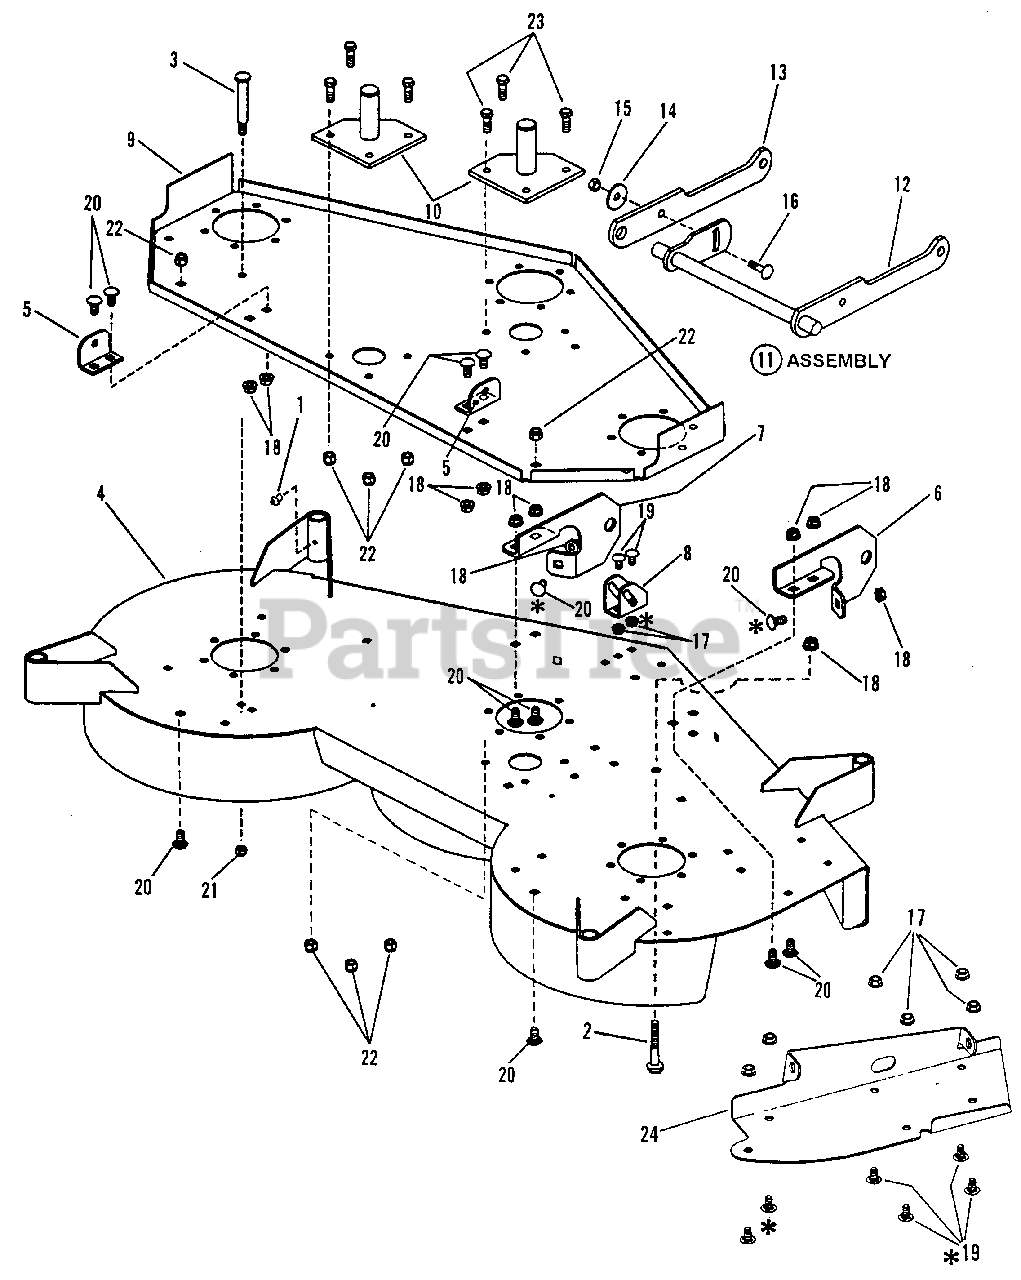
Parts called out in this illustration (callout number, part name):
1	LUBE FITTING, Straight (press-fit for .187 dia. Hole)
2	SCREW, 3/8-16 x 1-1/4" Hex Head Cap, Grade 5
3	BOLT, Gage Wheel
4	WELDMENT, Deck
5	BRACKET, Rear Lift-48" Deck
6	BRACKET, Front Hanger - R.H.
7	BRACKET, Front Hanger - L.H.
8	BRACKET, Front Hanger - 48" Deck
9	STIFFENER, 48" Deck
10	WELDMENT, Idler Pivot
11	ASSEMBLY, Front Lift Arm - 97 Model Year
12	WELDMENT, Front Lift Arm
13	ARM, Lift
14	WASHER, Cone 3/8" I.D.
15	NUT, 3/8-16 Hex
16	BOLT, 3/8-16 x 1-1/4", Grade 5
17	NUT, 5/16-18 Hex Flange Lock, Grade 5
18	NUT, 3/8-16 Hex Flange Lock
19	BOLT, 5/16-18 x 5/8" Short Neck Carriage, Grade 5
20	BOLT, 3/8-16 x 3/4" Short Neck Carriage, Grade 2
21	NUT, 5/16-18 Hex Nyloc
22	NUT, 3/8-16 Hex Nyloc
23	SCREW, 3/8-16 x 1" Hex Head Cap, Grade 5
24	BRACKET, Hinge
